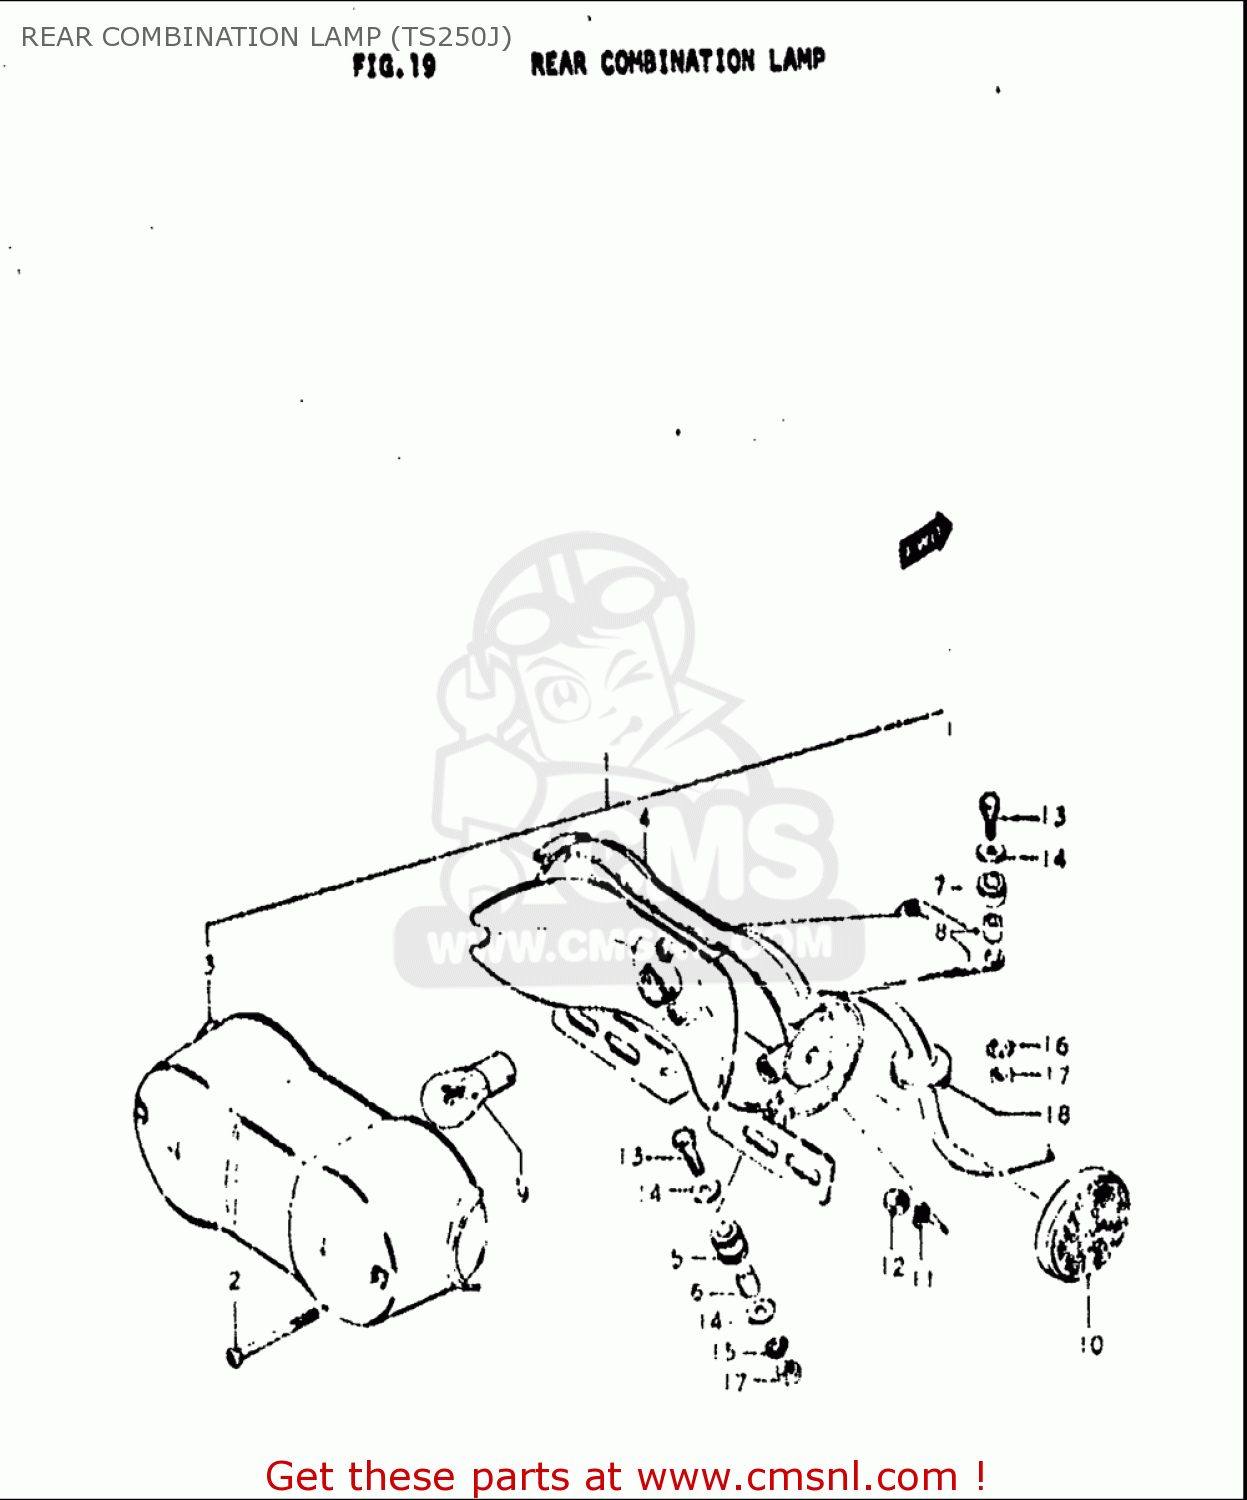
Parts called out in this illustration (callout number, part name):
2	SCREW
3	LENS,RR COMBINATION LAMP
5	CUSHION
6	SPACER
7	CUSHION
8	SPACER
9	BULB(6V17/5.3W,STANLEY,A4813)
11	WASHER,LOCK
12	NUT
13	BOLT
14	WASHER(6.5X20X1.2)
15	WASHER,LOCK
16	LOCK WASHER
17	NUT
18	GROMMET
